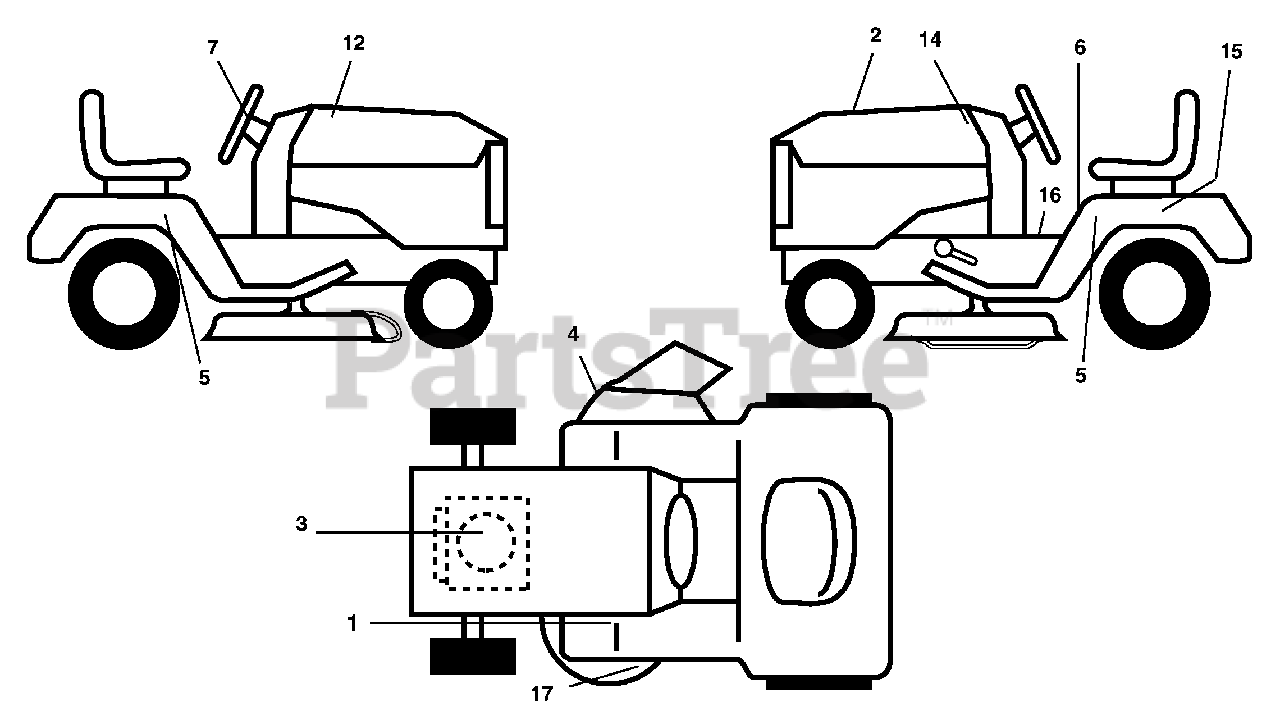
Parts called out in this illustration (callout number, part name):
1	Decal, Clutch/Brake Eng/Fr
2	Decal, Replacement
3	Decal, Engine HP
4	Decal Warning
5	Decal SDFNDR 5SP
6	Decal, Fender Danger English
7	Decal Ins Str Wh
12	Decal, Hood RH
14	Decal, Hood LH
15	Decal, Caution, Battery
16	Decal, Oper Sdl P/L Gear Dr Eng
17	Decal, V-Belt Sch.
17	Decal, Handle Lft Height Adj.
17	Manual, Operator's (E&F)
17	Manual, Parts (E&F)
